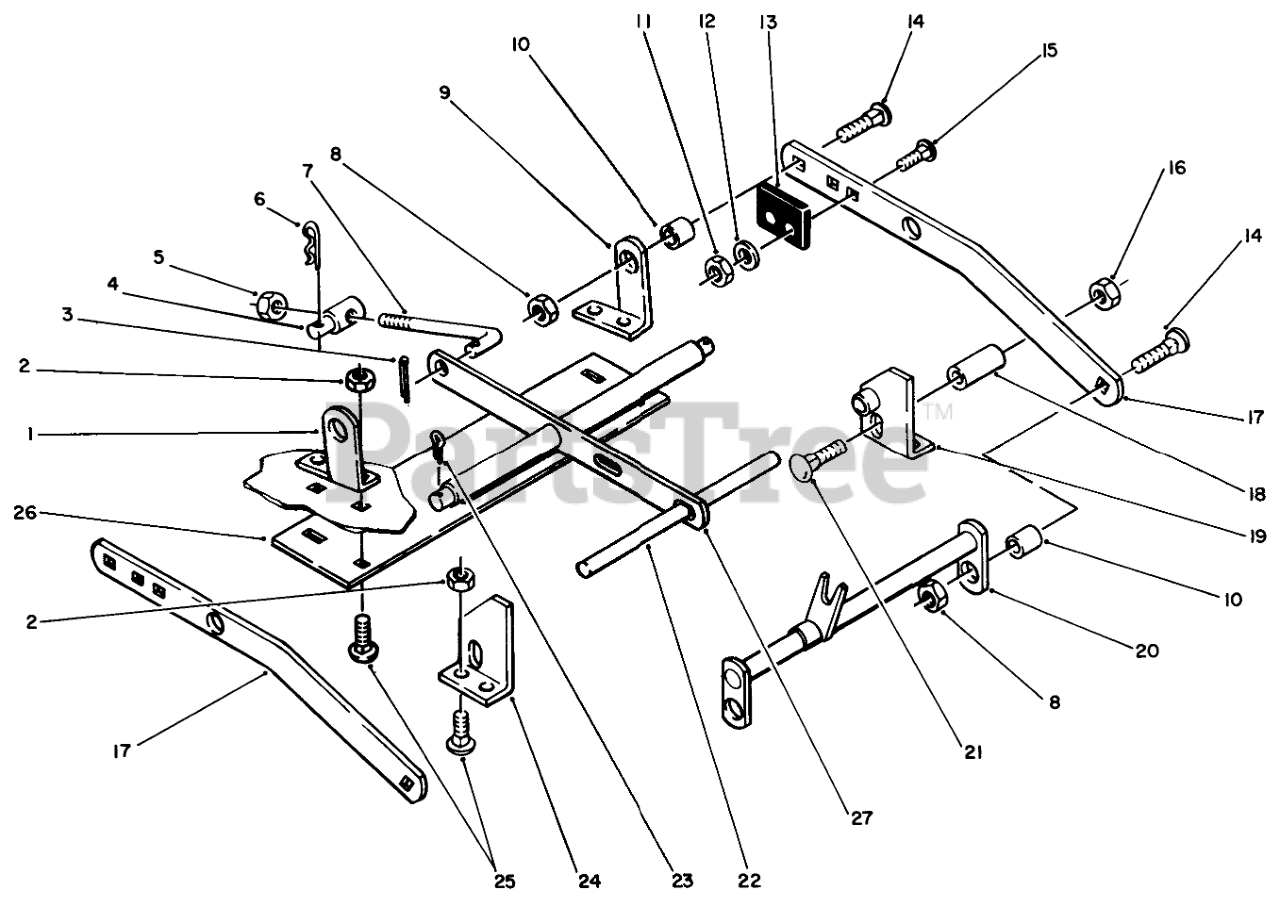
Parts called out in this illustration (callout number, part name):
1	Rear Bracket RH
2	NUT
3	Cotter Pin
4	TRUNNION-LIFT
5	NUT
6	Hairpin
7	ROD-LEVEL ADJUST
8	LOCKNUT-FLANGE
9	LH Rear Bracket
10	SPACER
11	Nut
12	Collar
13	BUMPER
14	Bolt
15	Bolt-Carriage
16	Nut
17	Bar Draft
19	Front Bracket LH
20	Hitch
21	CARRIAGE BOLT -4
22	Front Shaft
23	Cotter Pin
24	Front Bracket RH
25	Bolt
26	PLATE R
27	Leveler
